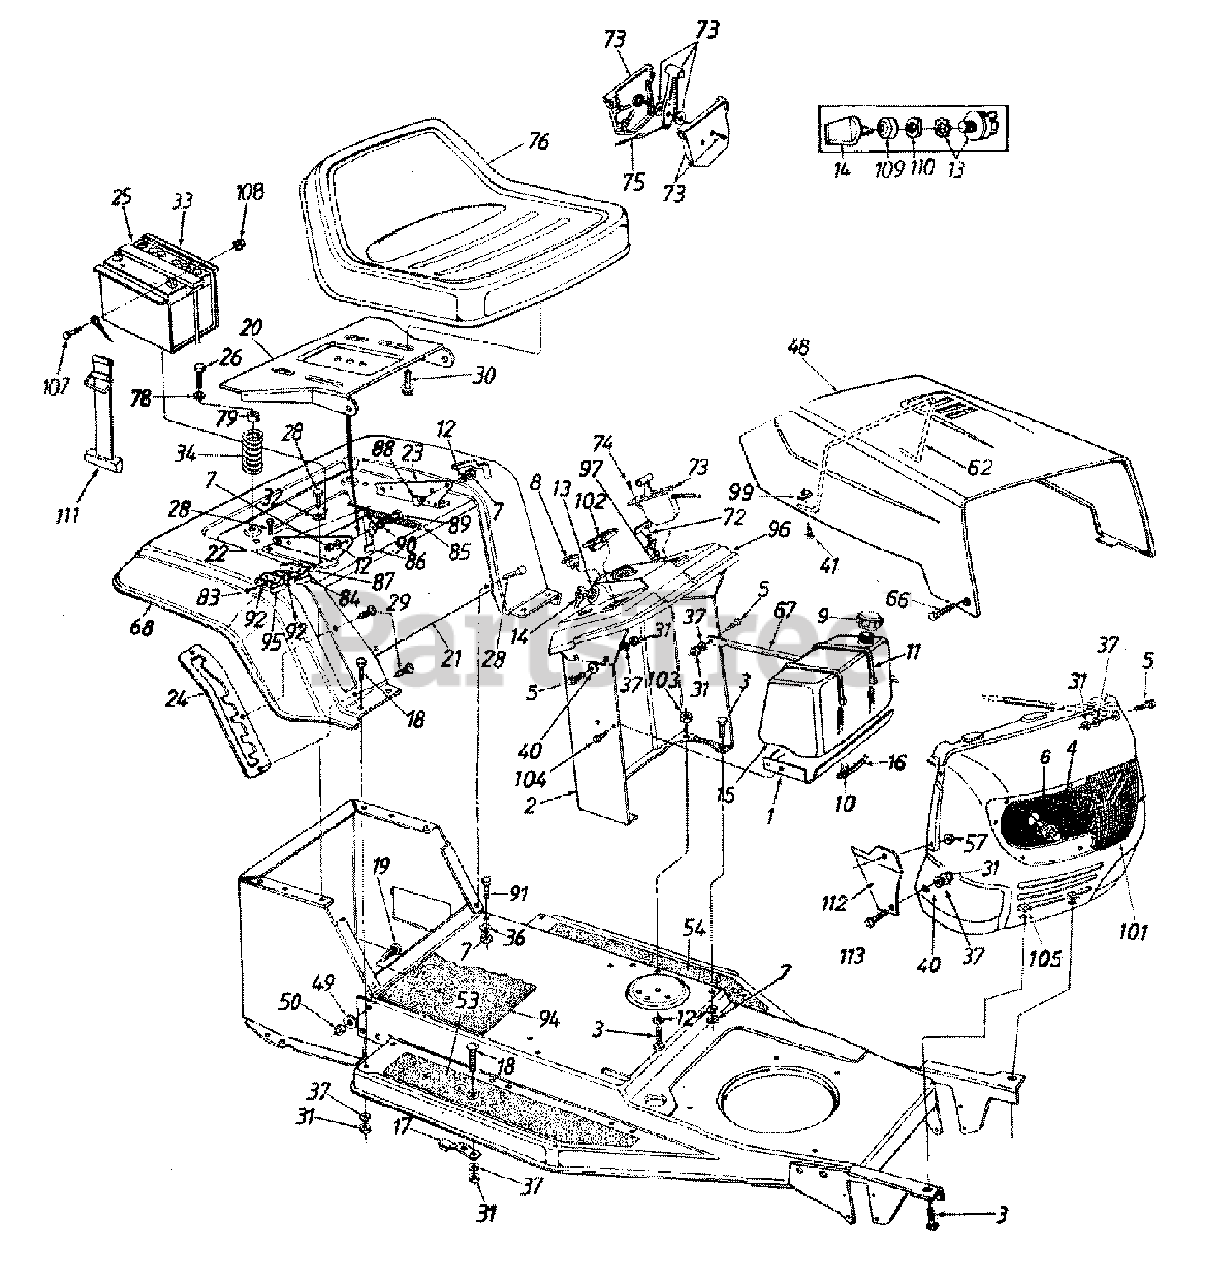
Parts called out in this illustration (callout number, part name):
4	Bulb
5	Hex Bolt 1/4 x .62" Lg.
6	Socket
7	Hex Nut 5/16-18 Thd.
8	Light Switch
9	Gas Cap
11	Cable Tie
12	L-Wash. 5/16" I.D.
13	Ignition Switch
15	Fuel Tank
16	Gas Line 15" Long
17	Blade Brake Ass'y.
18	Carriage Bolt 1/4-20 x .62"
19	Ribbed Neck Bolt 3/8-24 x .8"
25	Battery
26	Hex Self-Tap Screw 5/6-18 x 1.25" Lg.
27	Truss Mach. Scr. 1/4-20 x .75" Lg.
28	Hex AB-Tap Scr. 5/16 x .75" Lg.
29	Torx Mach. AB-Tap Scr. 1/4 x .62" Lg.
30	Hex Self-Tap Scr. 3/8-16 x .62" Lg.
31	Hex Nut 1/4-20 Thd.
32	External L-Wash. 5/16" I.D.
34	Compression Spring
36	Bell-Wash. 5/16" I.D.
37	L-Wash. 1/4" I.D.
40	Bell-Wash. .265" I.D. x .75"
41	Pan Hd. Scr. 10-24 x .75" Lg.
42	Fl-Wash. .218" I.D. x .62"
48	Hood
49	L-Wash. 3/8" I.D.-H.D.
50	Hex L-Nut 3/8-24 Thd.
52	Truss Mach. Scr. #10-24 x .5" Lg.
53	Foot Pad-R.H.
54	Foot Pad-L.H.
57	Lock Nut 1/4-20 Thd.
64	Hex Sems Nut #10-24 Thd.
65	Spr. Wash. .39" I.D. x .62" O.D.
66	Shld. Bolt
72	Choke Control
73	Throttle Control Box
74	Truss AB-Tap Scr. #10 x .5"
75	Throttle Wire
76	Seat Assembly
78	Fl-Wash. .344" I.D. x .88" O.D.
83	Hex Tap Scr. #8 x .5" Lg.
84	Safety Switch (Inner)
85	Ext. Spring 5.31" Lg.
86	Seat Lift Brkt.
87	Insulator Boss Plate
88	Shld. Bolt .437" Dia. x .162" Lg.
89	Shld. Bolt .437" Dia. x .268" Lg.
90	Spr. Wash. .445" I.D. x .75" O.D.
91	Hex Wash. Hd. Scr. 5/16-18 x .62" Lg.
92	Insulator Plate
94	Center Foot Pad
95	Safety Switch (Outer)
96	Dash Panel
97	Retainer Clip
98	Truss Mach. B-Tap Scr. #10 x .5" Lg.
99	Speed Nut
100	Internal Cotter Pin 5/16" Dia.
101	Lens
102	Ammeter
103	Hex Jam Nut 5/16-18 Thd.
104	Hex Wash. Hd. Tap Scr. 1/4-20 x .5"
105	U-Nut 5/16-18 Thd.
106	Ext. L-Wash. 1/4" I.D.
107	Hex Bolt 1/4-20 x .75" Lg.
108	Hex Sems Nut 1/4-20 Thd.
109	Ignition Cap
110	Ignition Nut 5/8-32 Thd.
111	Battery Strap
112	Side Panel-R.H.
113	Pan Hd. Mach. Scr. 1/4-20 x .5" Lg.
17933A-0498	PEDESTAL - OLD CUB YELLOW (0498)
17933A-0637	PEDESTAL - POWDER BLACK (0637)
17933A-0638	PEDESTAL - MTD/TROY-BILT RED (0638)
17933A-0648	PEDESTAL - TECH GRAY (0648)
17933A-0662	PEDESTAL - OYSTER GRAY (0662)
